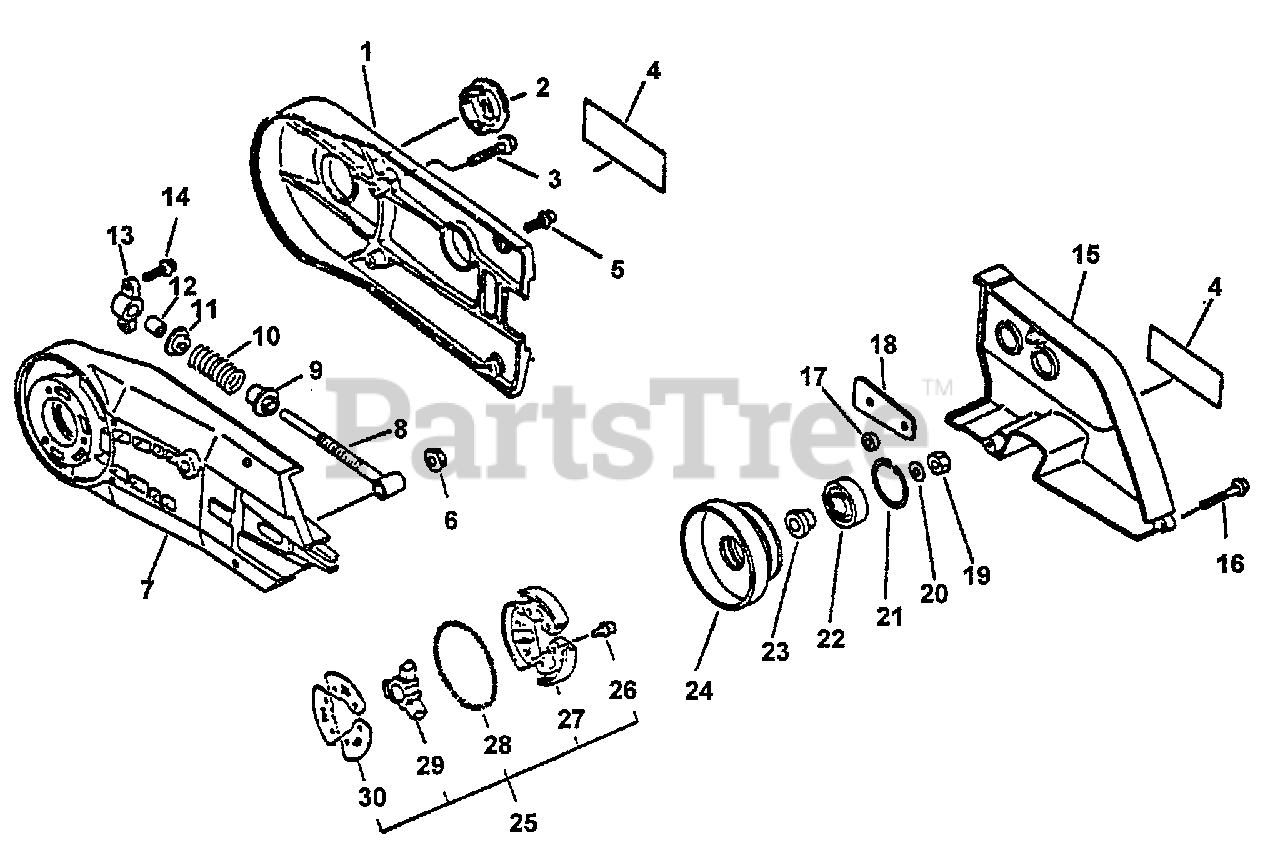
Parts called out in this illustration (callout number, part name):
1	COVER, V-BELT
2	COVER, CUTTER SHAFT
3	SCREW - 5X30
4	LABEL - ECHO
5	SCREW - 5X20
6	NUT - FLANGE
7	COVER, V-BELT
8	ROD, ADJUST
9	ADJUSTER
10	SPRING, ADJUST
11	SEAT, SPRING
12	SPACER, SHAFT
13	SUPPORT
14	SCREW - 5X20
15	COVER, ARM
16	SCREW - 4X35
17	WASHER - 8
18	SPACER, ARM
19	NUT - 8 -- LEFT HAND
20	WASHER, CLUTCH
21	RING, RETAINING - 32
22	BEARING, BALL - 6201
24	DRUM, CLUTCH
25	CLUTCH ASSY
26	SCREW - 4X8
27	CLUTCH SHOE SET
28	SPRING, CLUTCH
29	HUB, CLUTCH
30	PLATE, CLUTCH
